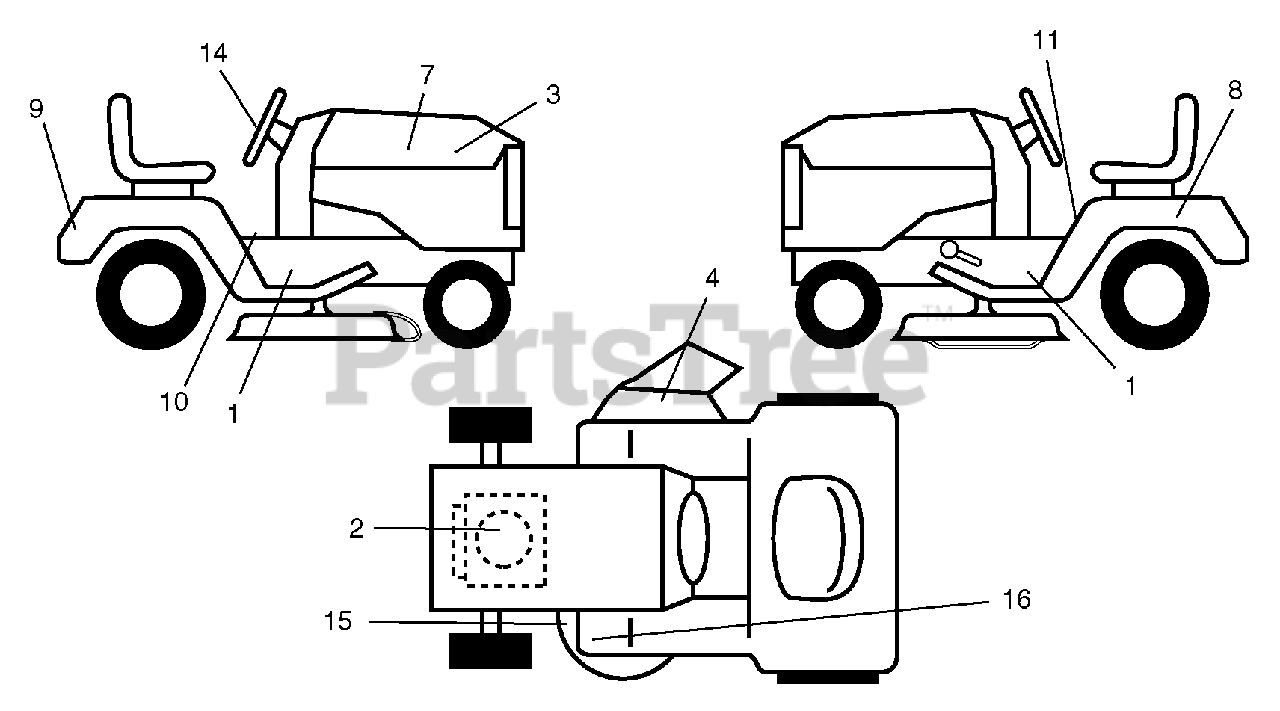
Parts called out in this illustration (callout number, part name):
1	Decal, Chassis
2	Decal, HP Engine
3	Decal, Hood RH
4	Decal, Deck
5	Decal, Hood LH
7	Decal, Replacement
8	Decal, Battery
9	Decal, Fender
10	Decal, Fender
11	Decal, Danger Fender Eng/Span
14	Decal, Steering Wheel
15	Decal, V-Belt Sch
16	Decal, Footrest
